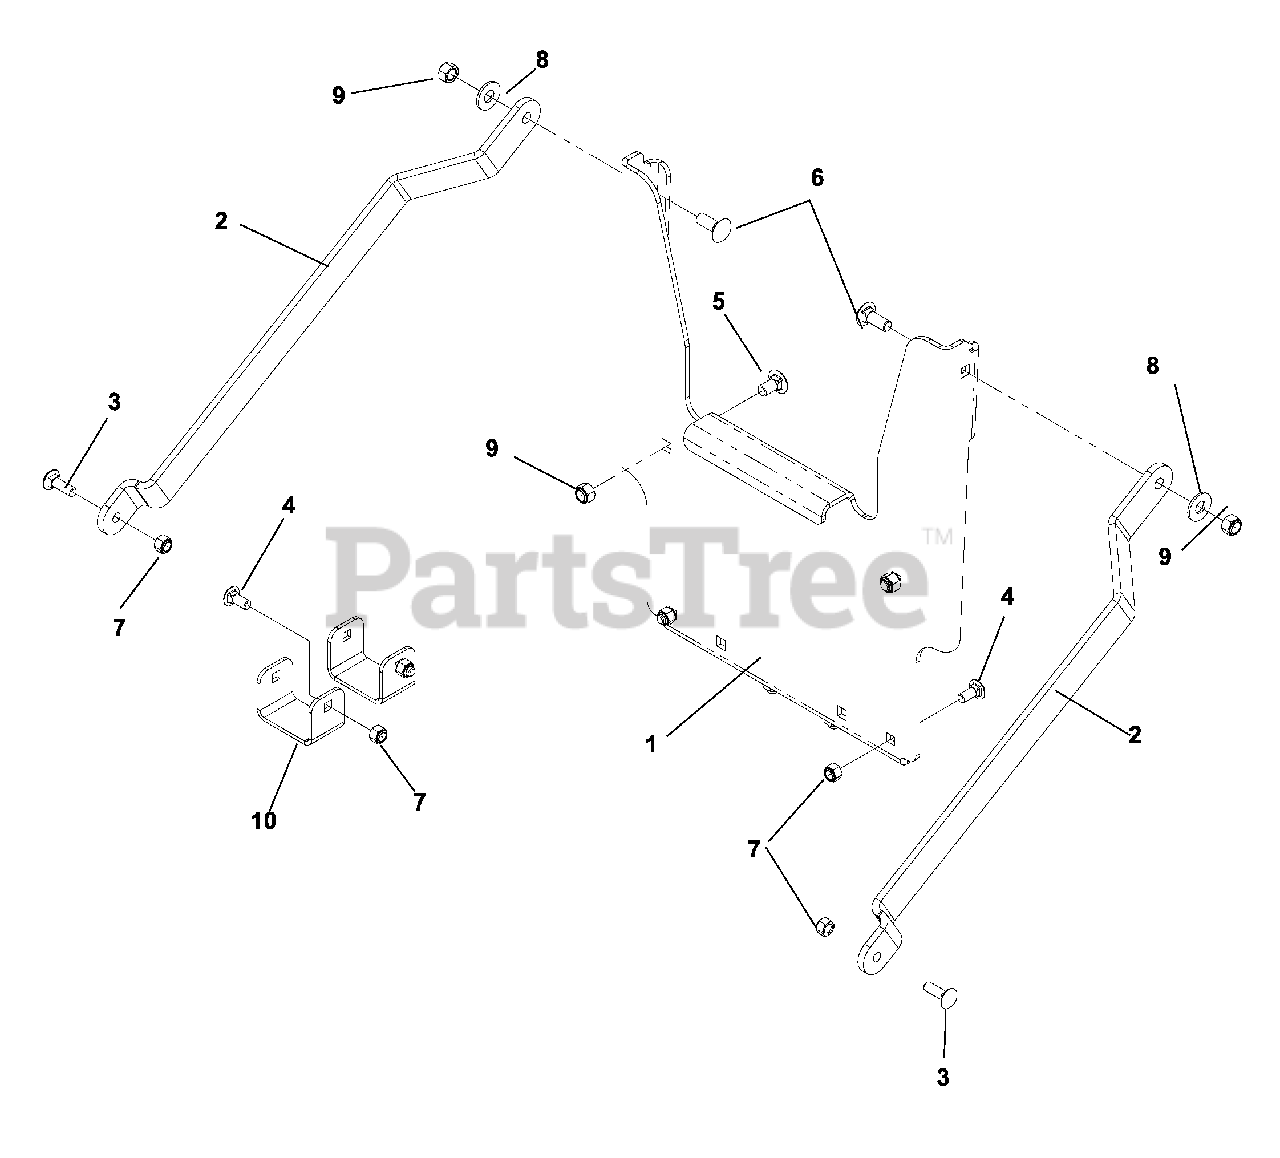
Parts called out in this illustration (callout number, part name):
1	PLATE, MOUNT, PAINTED
3	RHSNB 5/16C X 1
4	BOLT 5/16C X 3/4" CARRIAGE
5	RHSNB 3/8-16 X 3/4 GR5 ZD
6	RHSNB 3/8C X 1
7	NUT 5/16 NYLOC
8	WASHER 3/8 FLAT
9	NUT 3/8-16 NYLOC
10	EXTENSION, STRAP
